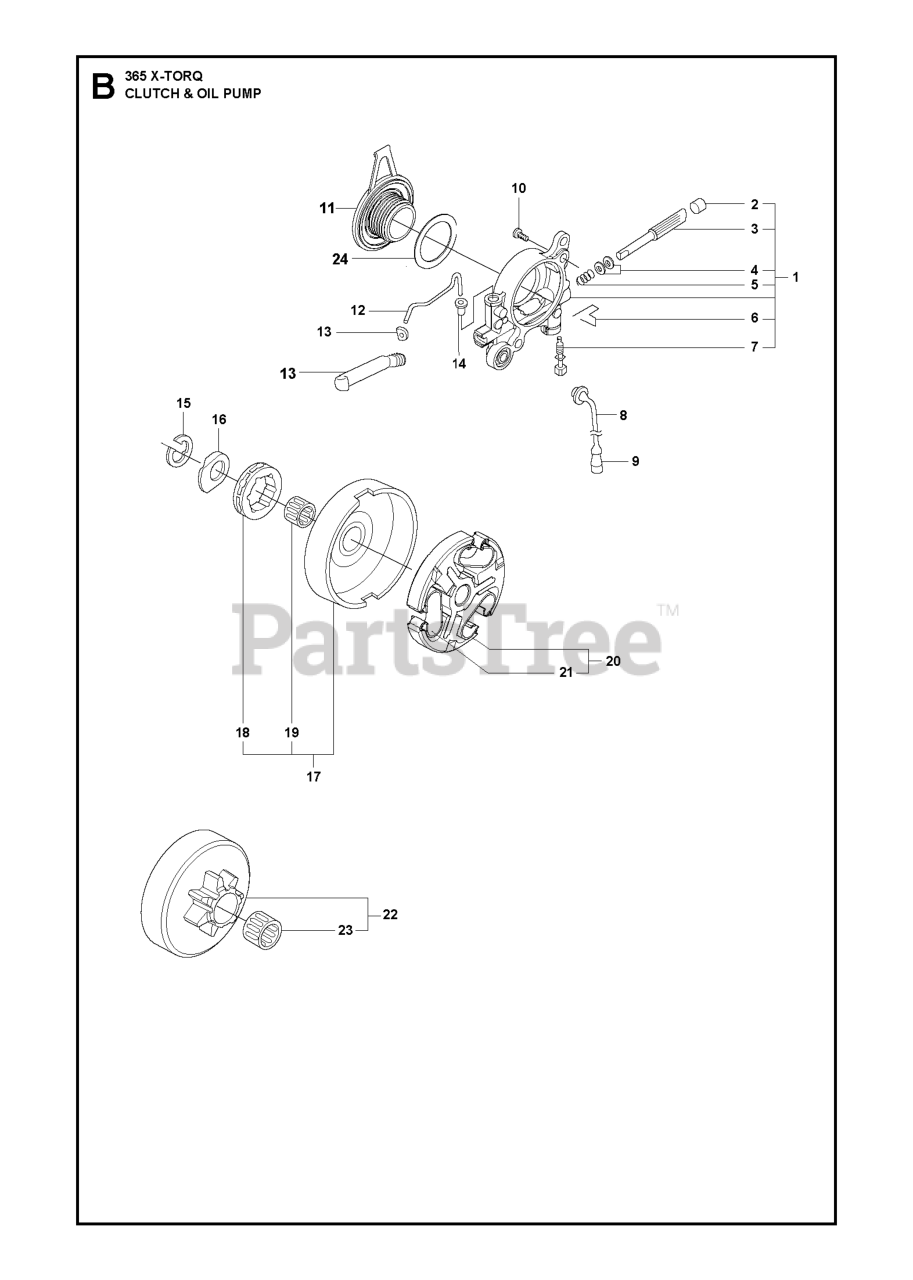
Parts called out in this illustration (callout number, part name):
1	OIL PUMP
3	PUMP PISTON
4	WASHER 6.1X9
6	SPRING CLIP
9	OIL SCREEN
10	SCREW ITXSCM M5X16 T27 12.9 T
11	PUMP PINION
13	OIL PRESSURE HOSE
13	GROMMET
15	RETAINING RING
17	CLUTCH DRUM ASSY
18	68210 RIMSPROCKET
18	22273 Sprocket 3/8"x8T
19	CLUTCH DRUM BEARING
20	CLUTCH ASSY M14X1.25-6H
22	CLUTCH DRUM
23	CLUTCH DRUM BEARING
